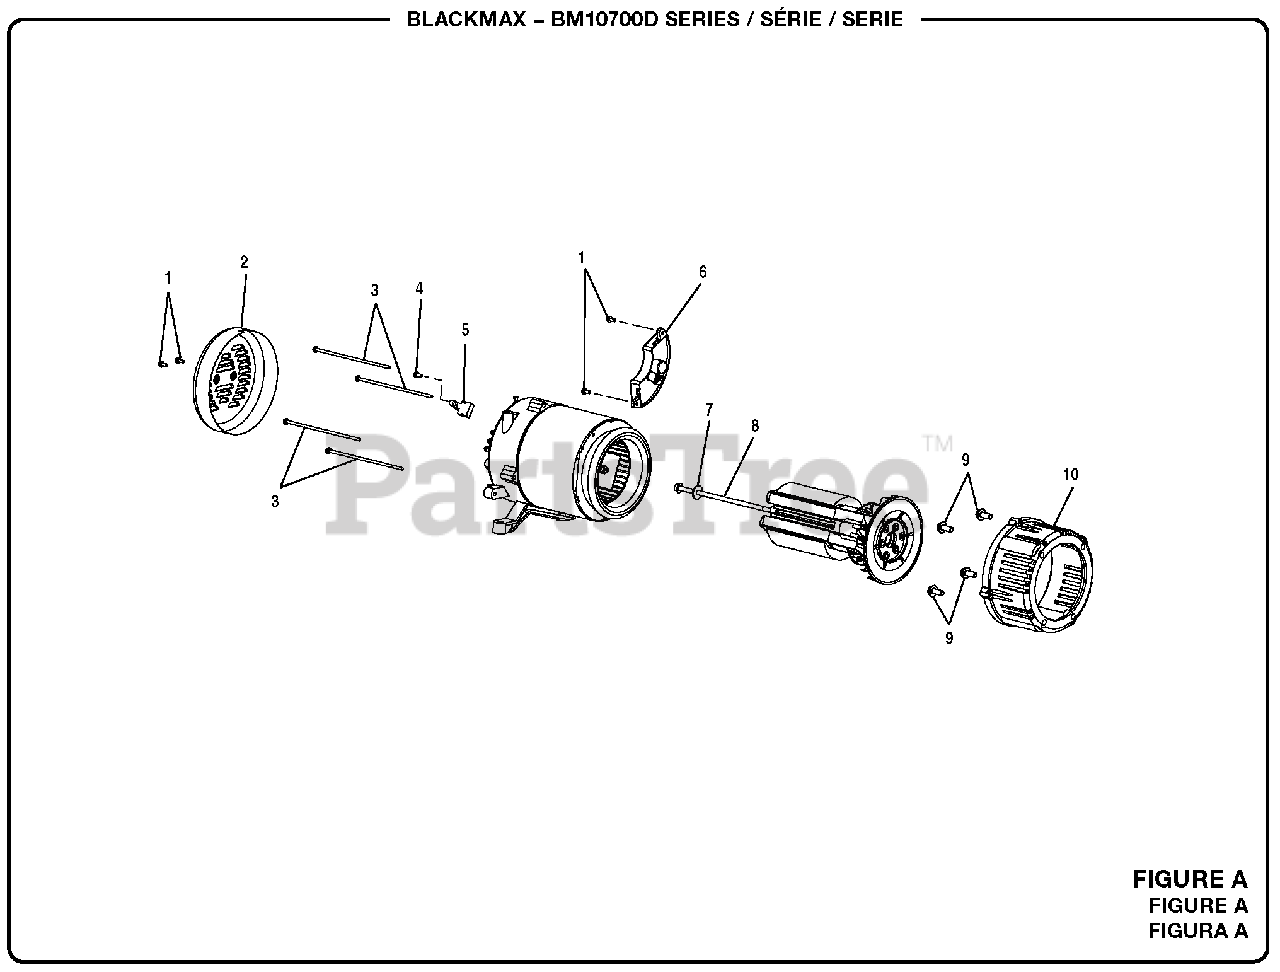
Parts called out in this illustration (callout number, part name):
2	Brush Cover
3	Bolt (1/4-20 x 6 in.)
4	Bolt (Brush Assembly)
5	Brush Assembly
6	Automatic Voltage Regulator
7	Lock Washer (5/16 in.)
8	Bolt (5/16-24 x 9-1/2 in., Hex. Hd.)
9	Bolt (3/8-18 x 1-1/4 in.)
10	Engine Adapter
